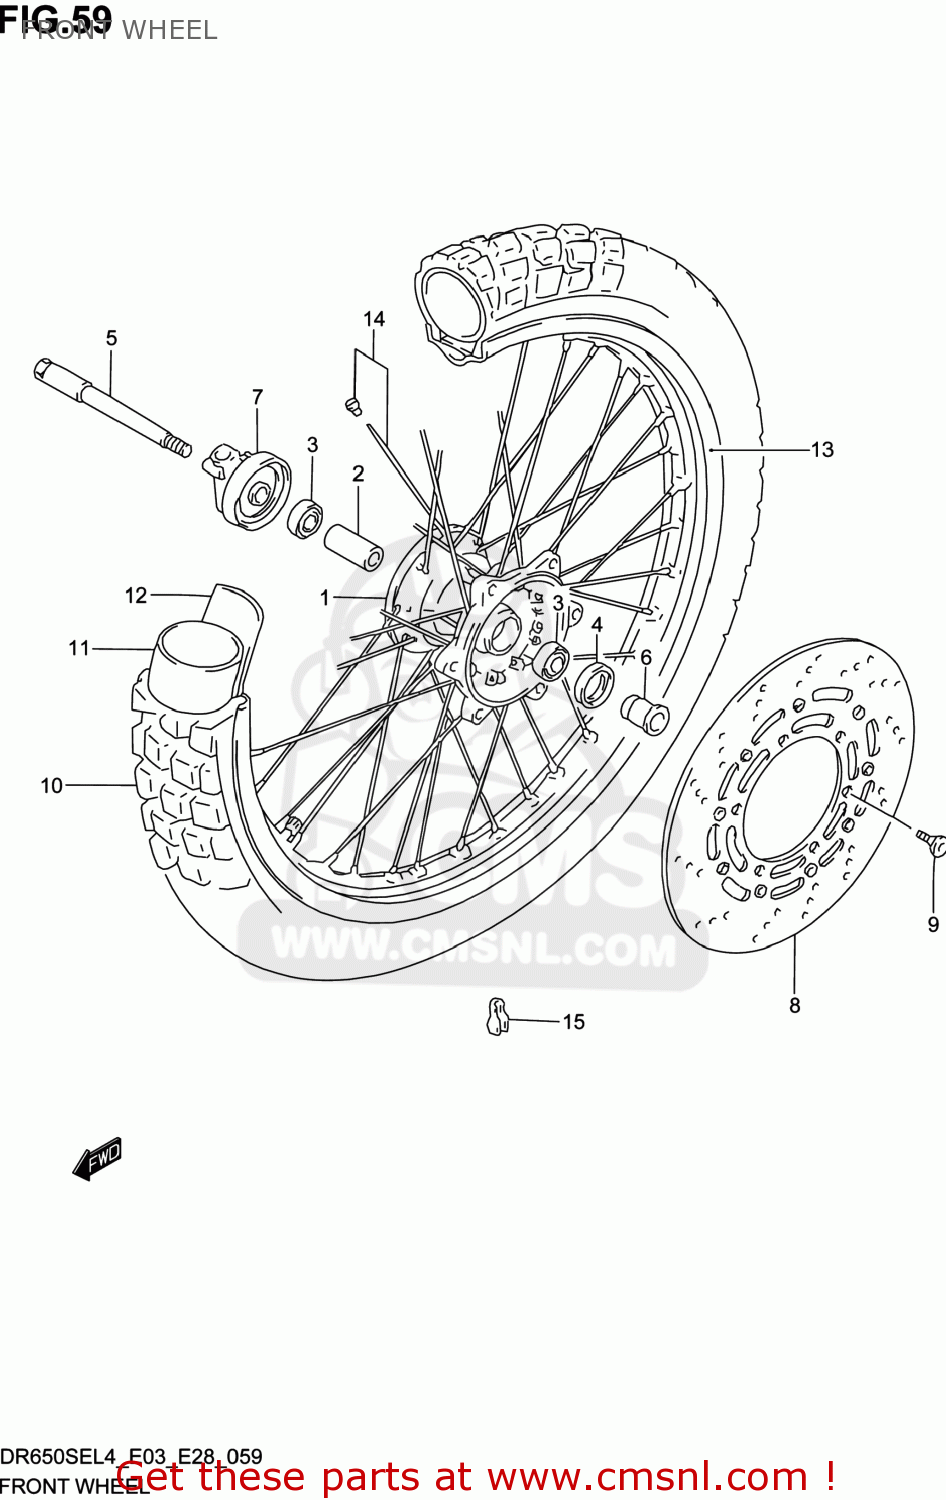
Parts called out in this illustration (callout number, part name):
1	HUB,FR WHEEL
2	SPACER,FR HUB BEARING
3	BEARING
4	SEAL,OIL(23X35X6)
5	AXLE,FR
6	SPACER,FR AXLE,L
7	BOX ASSY,SPEEDOMETER GEAR
8	DISC,FR BRAKE
9	BOLT(8X20)
10	TIRE,FR(90/90-21 54S)
11	TUBE ASSY,WHEEL INNER
12	PROTECTOR,WHL INR TUBE
13	RIM,FR WHEEL(21X1.85)
14	SPOKE SET,FR WHEEL
15	BALANCER,WHEEL(20G)
